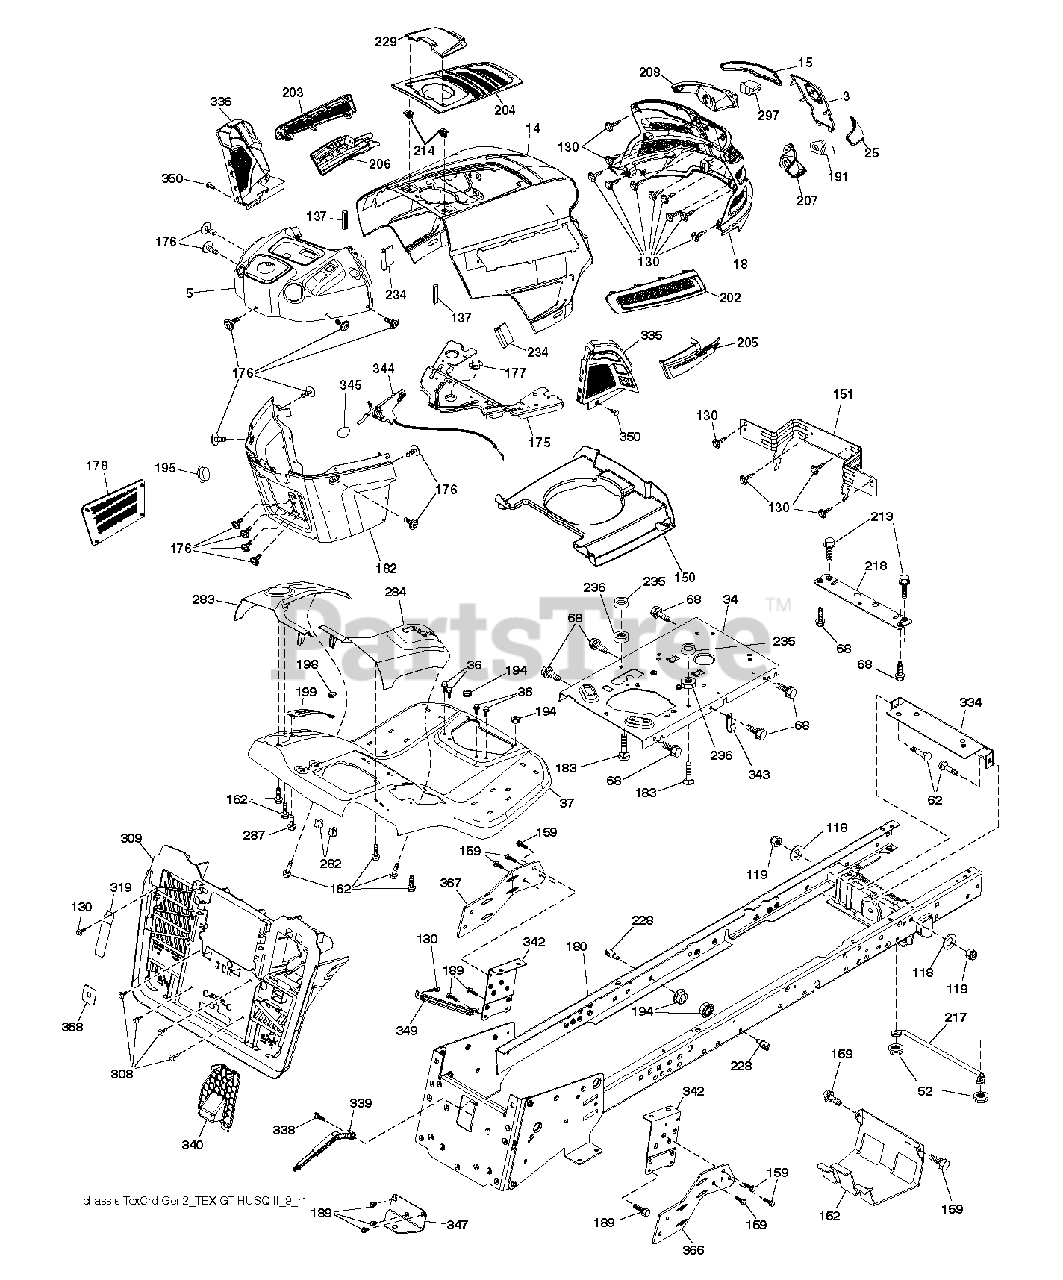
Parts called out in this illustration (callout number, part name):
3	APPLIQUE.SUBASM.GT.HUSQ.II
5	GT2.DASH.UPPER.W/BUMPERS
14	HOOD.ASM.HUSQVARNA.GT.TEX.ORAN
15	LENS.HEADLIGHT.LH.GTII.2011
18	GRILLE.SUBASM.GT.HUSQ.II
25	LENS.HEADLIGHT.RH.GTII.2011
34	PLATE.ENGINE.10GA.CRD.GENII
36	SCREW 5/16"
37	FENDER.TEX.SRD.CRD.BASE
52	LOCKNUT
62	BOLT D
68	SCREW LT
118	WASHER
130	SCREW.#10 X 0.750.BOS
137	BUMPER DASH
150	AIR.DUCT.GTV.BLACK
151	BRACKET.PIVOT.HOOD.GT.HUSQ.II
152	SHIELD.BROWNING.PNT.GT.V2
159	SCREW, 3/8-16X3/4
162	SCREW.HI-LO.CONSOLE
175	PLATE.CROSSMEMBER.HUSQ
176	SCREW.#10-24X5/8.RN.QU
177	BUSHING, STEERING
178	CARGO.ASM.NET.TXGT.W/C
180	WELDMENT.CHASSIS.TEX.CRD.GEN.2
182	DASH DASH LOWER
183	BOLT.5/16-18X1-1/4 FULL THD
189	SCREW
191	INSERT.REFLECTIVE.RH.HUSQ.GTII
194	NUT LOCK HEX FLANGE 5/16-18
195	PLUG.HOLE.DASH.LOWER.12V.BLK
198	INDICATOR.DECK.LIFT.RED
199	PLATE DECK LIFT
202	VENT.SIDE.RH.GT.HUSQ.II.
203	VENT.SIDE.LH.GT.HUSQ.II.498
204	VENT.TOP.EXTERNAL.FILL.GT2.GRE
205	SIDE.TRIM.RH.GT.HUSQ.II
206	SIDE.TRIM.LH.GT.HUSQ.II.GRAY
207	BEZEL LIGHT.RH.GT.II.MYLAR
208	BEZEL LIGHT.LH.GT.II.MYLAR
213	BOLT
214	CLIP.RETAINER.TINNER.
217	ROD.PIVOT.HOOD
218	X-PIECE.HOOD.STOP.NON/
228	STUD.FASTNER.W/ANTI-ROTATE
229	LID.EXT.FILL.GT.HUSQ2.BLACK
234	BUMPER.HOOD.TEX.HUSQVARNA
235	SPACER FENDER
236	NUT.CENTERLOCK.5/16-
282	CLIP.RETAINER.CONSOLE.LT.HUSQ
283	CONSOLE.DECKLIFT.CRDII.498
284	CONSOLE.PEDAL.HYDRO
287	SCREW 1/4X20
297	INSERT.REFLECTIVE.LH.HUSQ.GTII
308	BOLT, 5/16-18 X 1 3/4
309	BACKPLATE.SUBASM.SERV.TEX.CRD.
319	LEVER.BAG.CRDII.ANTIROTATION
334	BRACKET.ENGINE
335	COVER.LOWER.DASH.RH.BLACK
336	COVER-LH.LOWER.DASH.GT2.BLACK
338	BOLT BOLT SHOULDER
339	.WITCH.FULL BAGGER.INDICATOR
340	BATTERY.DOOR.TEX.CRD.GEN.2,1
342	SUPPORT SUPPORT FENDER
343	CLIP CLIP
344	CONTROL.EZ.MULCH.TEX/CRD
345	RP KNOB.OVAL.TAPERED.3/8-16BLK
347	HITCH HITCH TOW TEX CRD GEN 2
349	BRACKET.SUPPORT.LRVB/CRD
350	CLIP.X-MAS.TREE
366	BRACKET.RH.FRONT.BAGGER.BLACK
367	BRACKET.LH.FRONT.BAGGER.BLACK
368	FULL.LEVER.BAGGER.TEX.CRD
